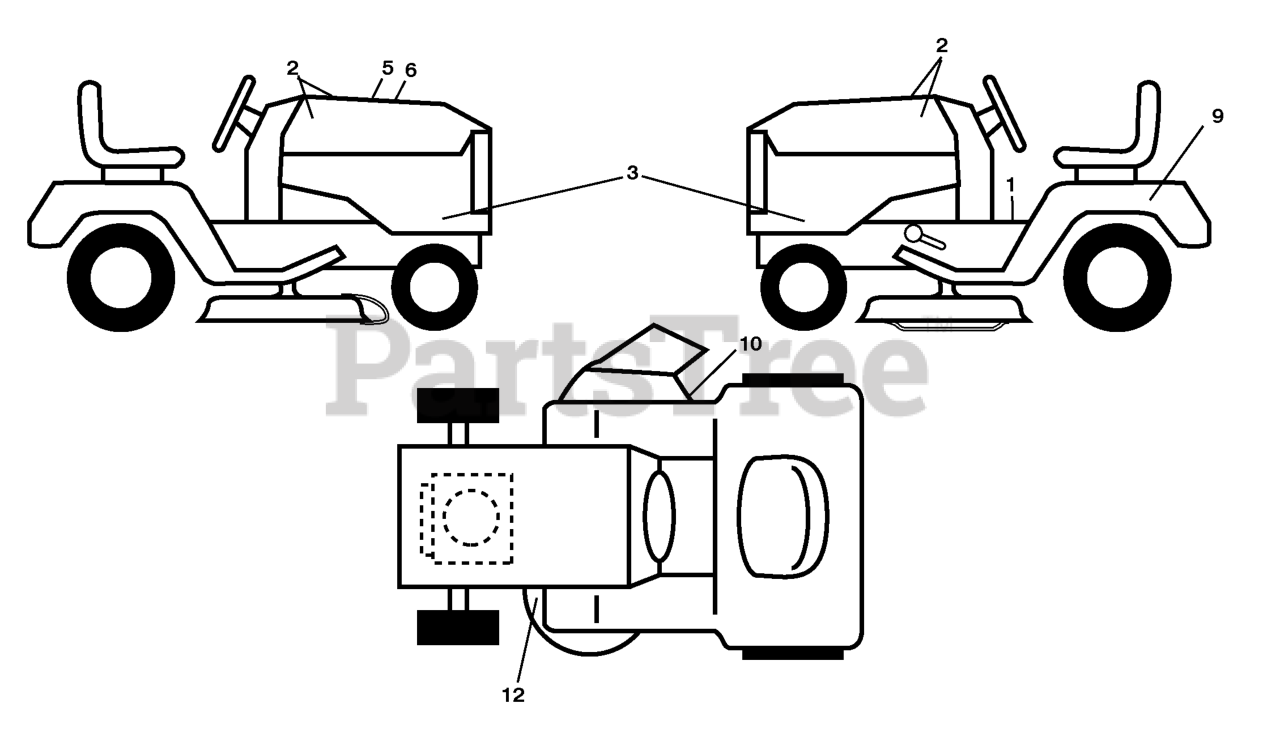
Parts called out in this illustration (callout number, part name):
1	DECAL.FENDER.WARNING.ENG
2	RP.DECAL.BADGE.170MM.TEXTLOGO
3	DECAL, HOOD PANEL SD
5	DECAL.WARNING.CUST.RESP.E85.
6	Decal, Replacement
9	DECAL BTRY SYMBOLS
10	DECAL.WARN.KEEP.HAND.AWAY
12	DECAL V BELT SCHEMATIC
